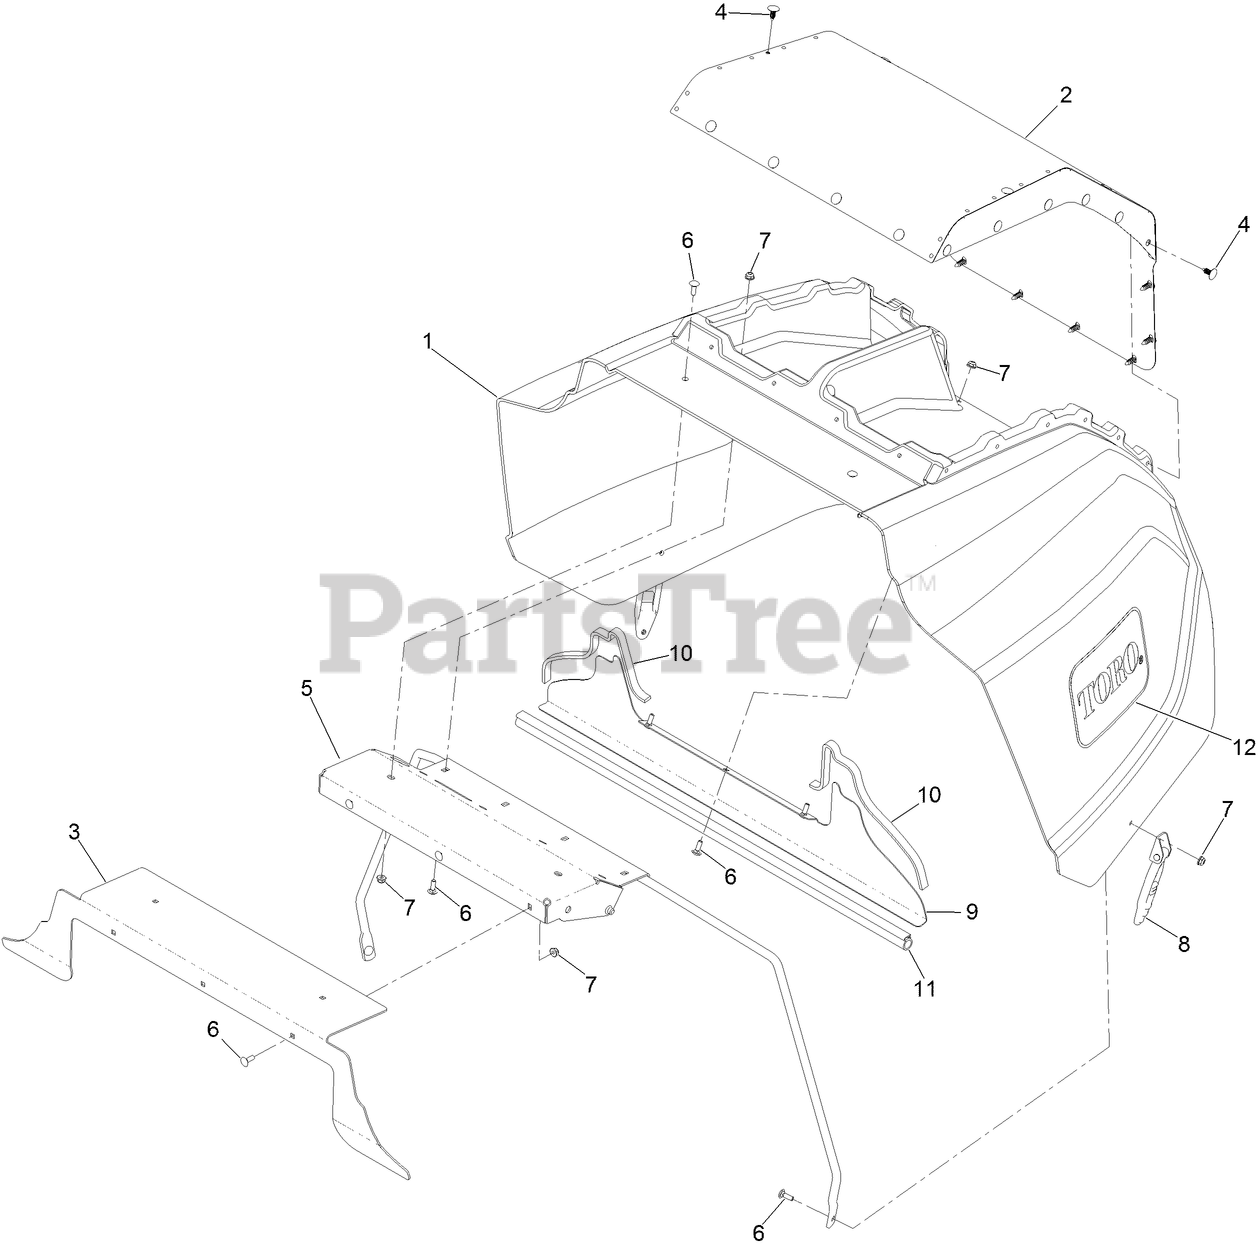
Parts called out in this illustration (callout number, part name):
2	SCREEN-INTAKE
3	BLOCK OFF-HOOD
4	PLUG-PLASTIC
5	SUPPORT-HOOD
6	BOLT-CARR
7	NUT-HF
8	LATCH-RUBBER
9	PLATE-SEAL
10	SEAL-FOAM
11	SEAL-BULB
12	DECAL
